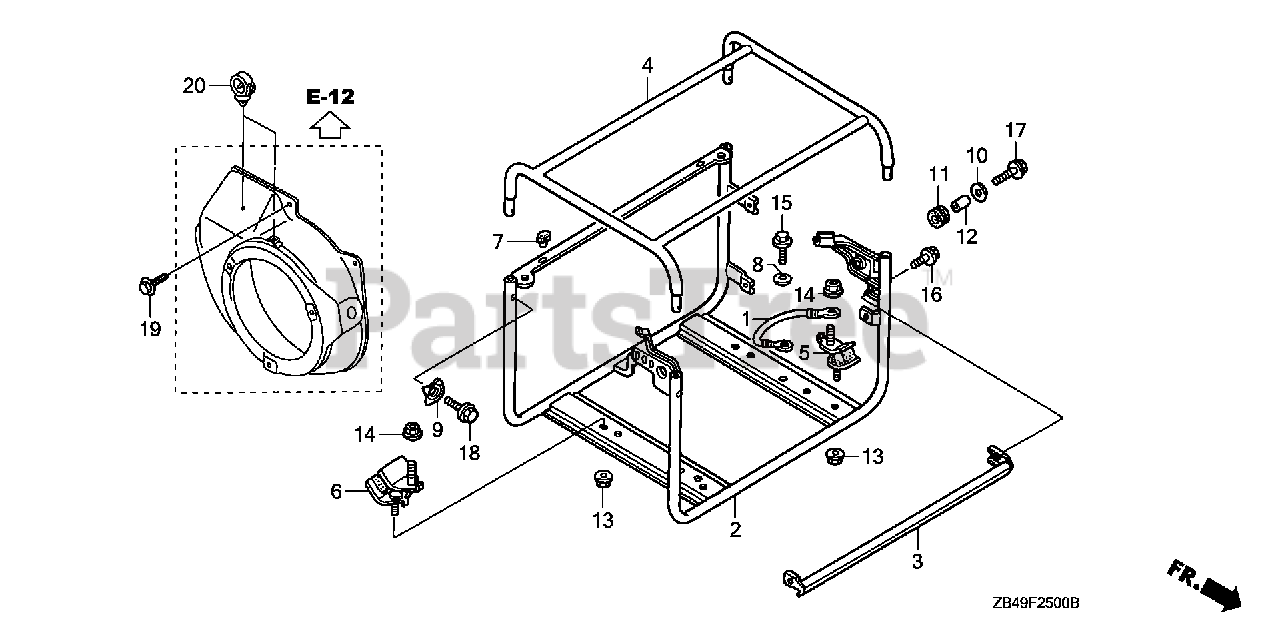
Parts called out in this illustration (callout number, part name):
1	CABLE, GROUND
2	FRAME (LOWER) *NH105* (MAT BLACK)
3	CHANNEL, FR. *NH105* (MAT BLACK)
4	FRAME (UPPER) *NH105* (MAT BLACK)
5	RUBBER (LOWER)
6	RUBBER (LOWER)
7	STOPPER, DISCHARGE GUARD
9	WASHER, FRAME JOINT
11	RUBBER, CONTROL BOX
12	COLLAR, CONTROL BOX
13	NUT, FLANGE (8MM)
14	NUT, FLANGE (10MM)
15	BOLT, FLANGE (6X10)
16	BOLT, FLANGE (6X12)
17	BOLT-WASHER (6X20)
18	BOLT, FLANGE (8X16)
